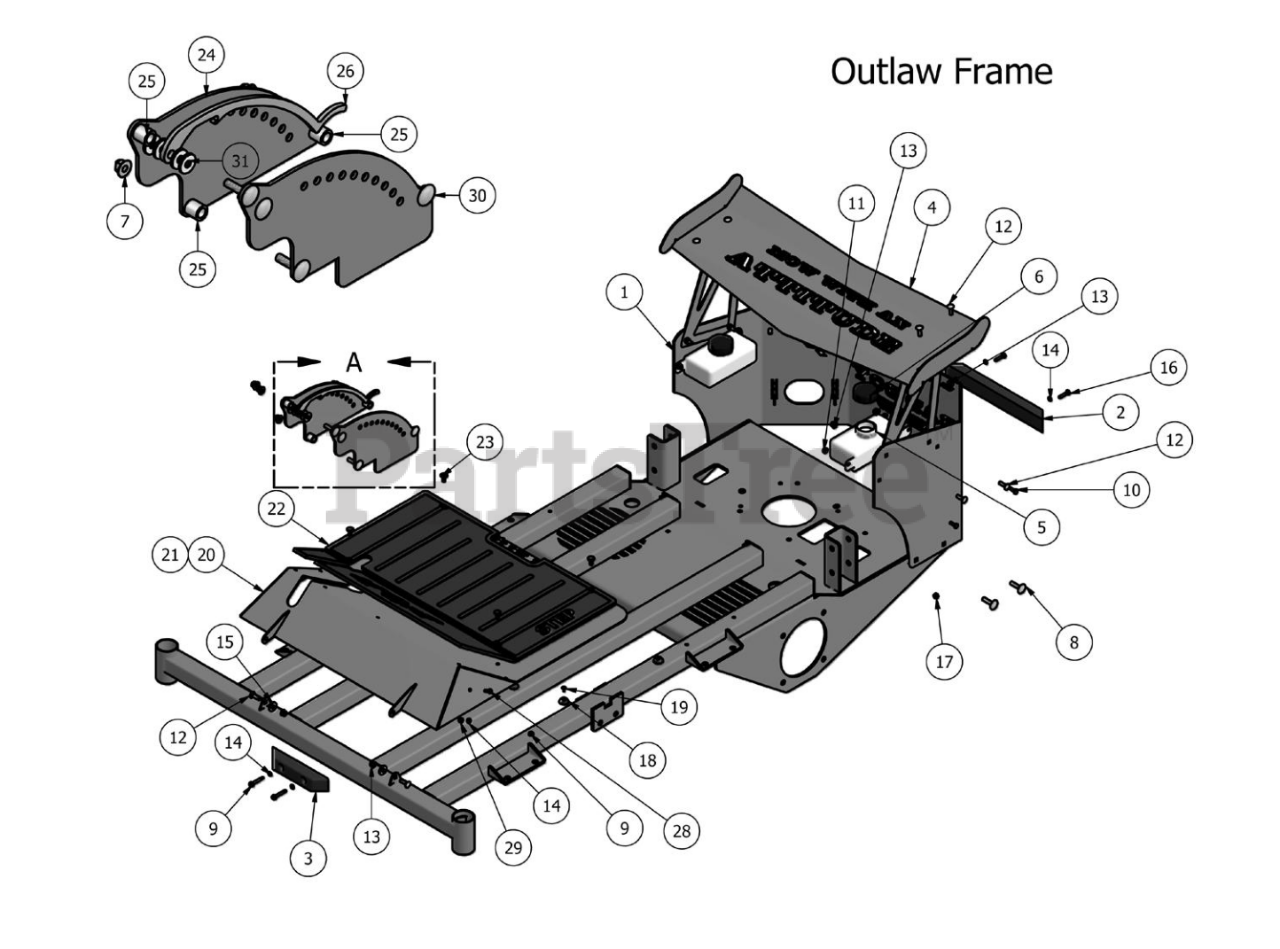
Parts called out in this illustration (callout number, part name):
1	Outlaw Rear Plate
4	Spoiler Assembly
5	Expansion Tank Outlaw
6	ZT Hydraulic Tank Cap
7	3/8 Nylock Flange Nut
8	3/8" x 1-1/4" Carriage Bolt
9	14 x 1-1/2 HWA A T/S Screw
10	1/4-20 x 3/4 Grade 5 Hex bolts Zinc
11	1/4-20 Hex Flange Nuts Zinc W/Serrations
12	5/16-18 x 1 Carriage Bolts Zinc
13	5/16-18 Nylon Insert Flange Nut Zinc Orange Nylon
14	1/4" Flat Washer
15	.360ID Plastic Washer
16	1/4-20 x 1-1/4 Grade 5 Hex bolts Zinc
17	1/4-20 Nylon Insert Locknut Zinc Orange Nylon
18	15/16 DIA Recessed Bumper Rubber BLK
19	10 x 1/2 Pan Phillips Machine Screw
20	Outlaw Floor Board
21	Floor Cable
22	Foot Assist Floor Mat
23	Ratchet Fastener-Floorboard
24	Outlaw Height Ind. Plate (Outer)
25	3/40D x 1/2ID x 3/4 Spacer
26	Outlaw Deck Lever Lock
28	1/4-20 x 1/2 Buttonhead Socket C/S 18-8 SS
29	1/4-20 Hex Nuts Zinc
30	3/8 x 1-1/2 Carriage Bolt
31	.39 Plastic Washer
